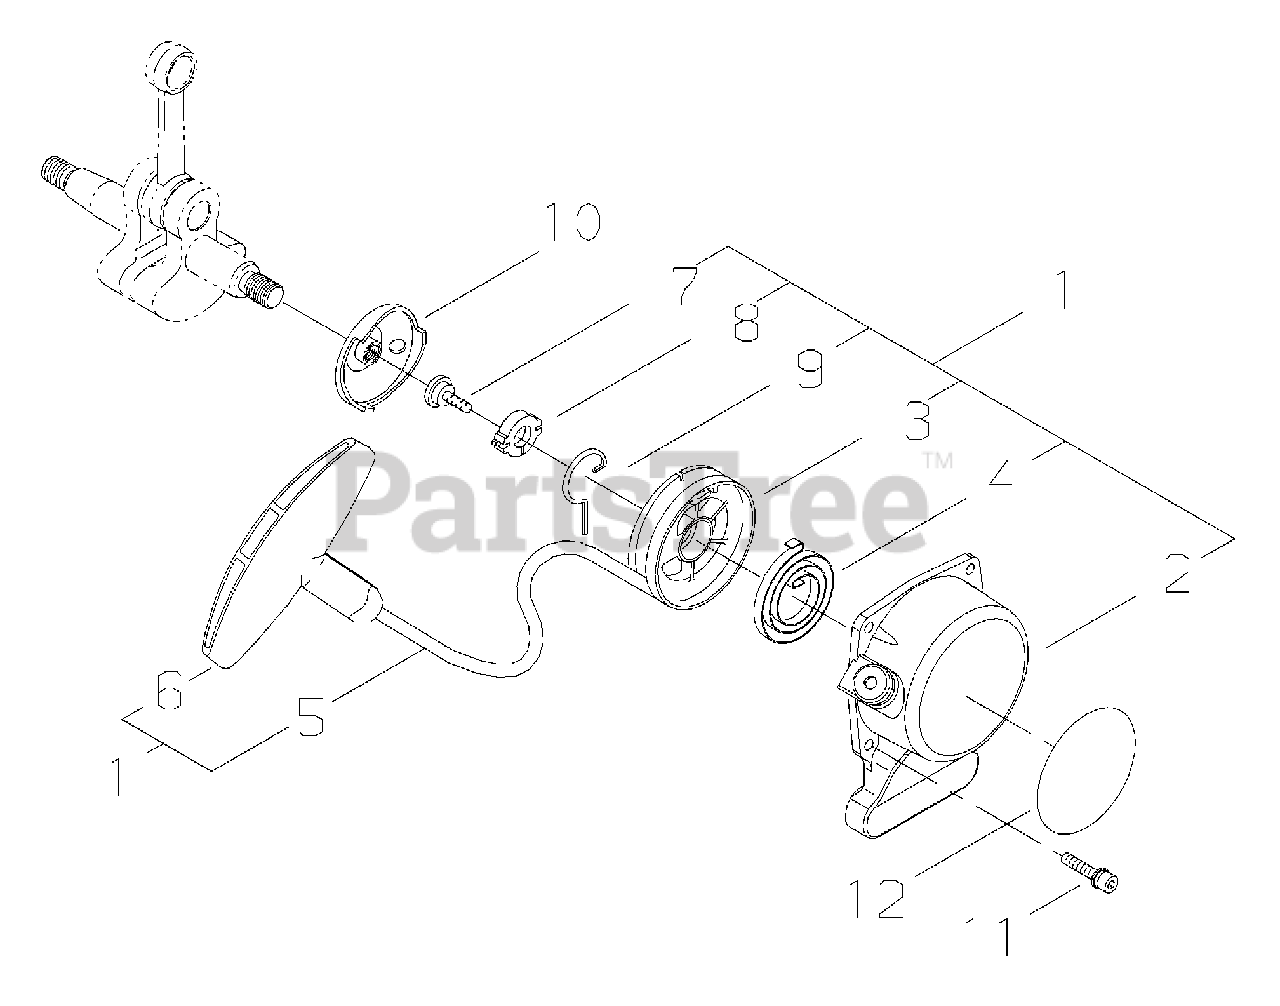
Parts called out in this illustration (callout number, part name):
1	STARTER ASSY, RECOIL
2	CASE, RECOIL STARTER
3	REEL, ROPE
4	SPRING, RECOIL
5	ROPE, STARTER
6	GRIP, STARTER
7	SCREW 5
8	WASHER 5
9	ARM, SWING
10	PULLEY, STARTER
11	BOLT M4×14
12	LABEL, RECOIL C4
